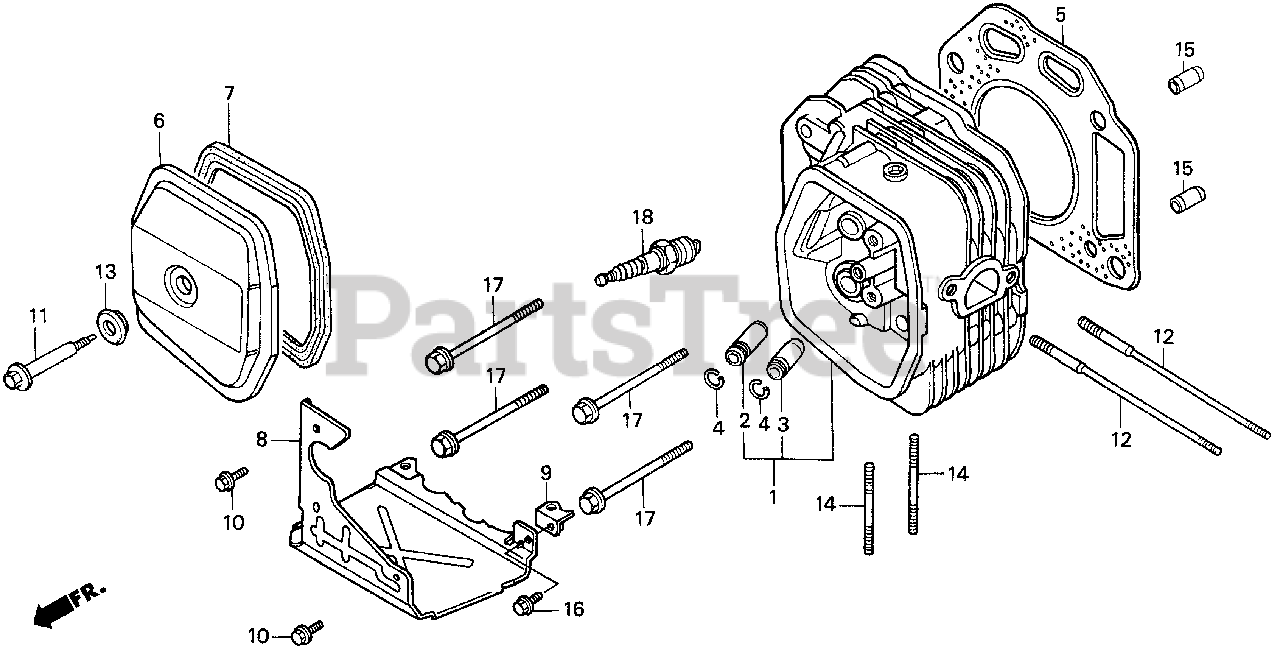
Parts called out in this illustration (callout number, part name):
1	CYLINDER HEAD
2	GUIDE, VALVE (OS)
3	GUIDE, EX. VALVE (OS)
4	CLIP, VALVE GUIDE
5	GASKET, CYLINDER HEAD
6	COVER, HEAD
7	GASKET, CYLINDER HEAD COVER
8	COVER (LOWER)
9	STAY, COVER (LOWER)
10	BOLT, FLANGE (6X12) (CT200)
11	BOLT, HEAD COVER
12	BOLT, STUD (8X131.5)
13	WASHER, HEAD COVER
14	BOLT, STUD (8X32)
15	PIN A, DOWEL (12X20)
16	BOLT, FLANGE (6X12)
17	BOLT, FLANGE (10X80)
18	SPARK PLUG (BPR5ES) (NGK)
